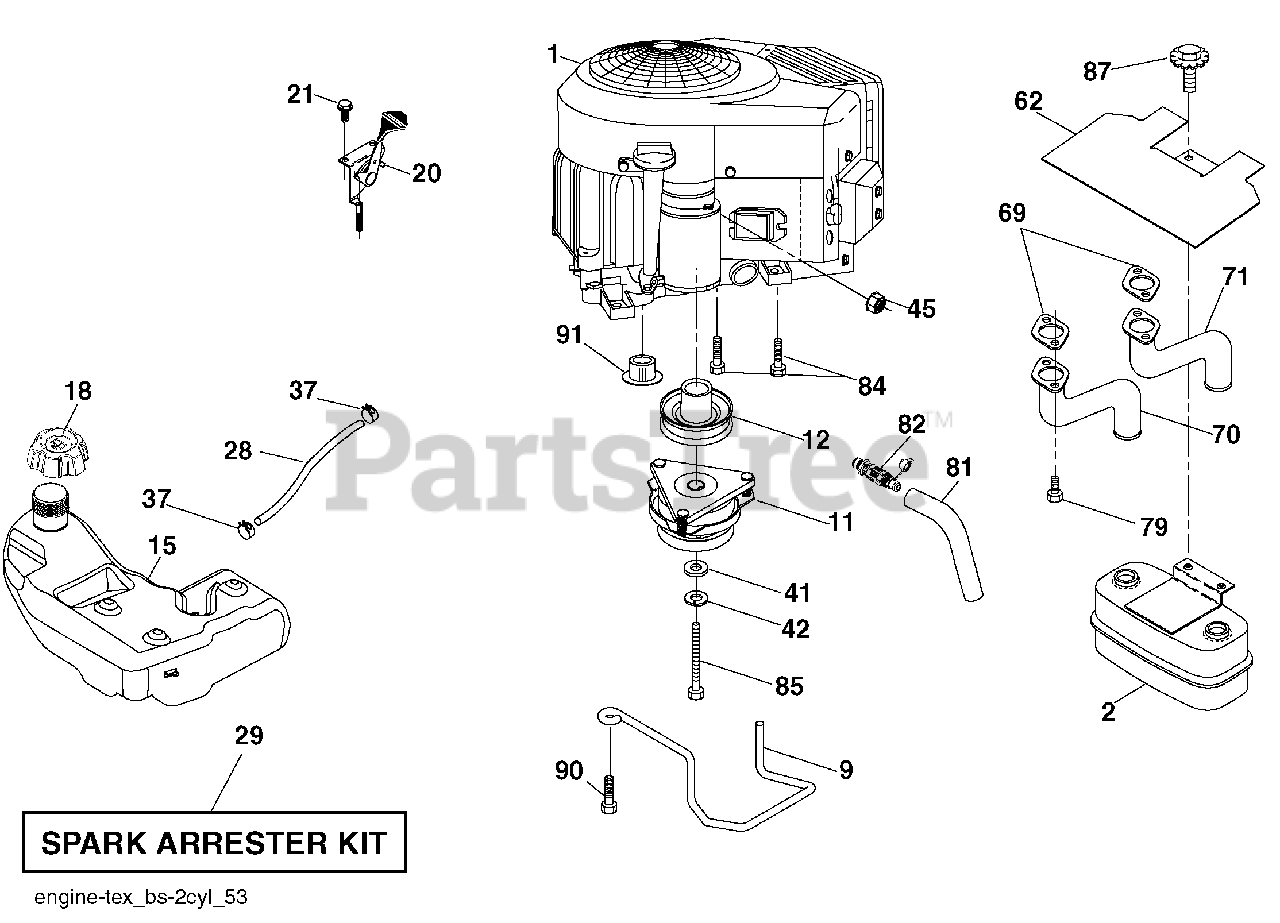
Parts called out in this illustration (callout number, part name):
2	Muffler
9	Keeper Belt Engine
11	Clutch Electric
12	Pulley Engine
15	Tank Fuel 3.0
18	Cap Asm
20	Control Throttle
21	Screw #10 x 0.750 BOS Thread
28	Fuel Line
29	Spark Arrester Kit
37	Clamp Hose
41	Washer 1-1/2 x 15-32 x .250
42	Washer Lock 7/16
45	Nut Keps Hex 1/4-20 unc
62	Shield Heat Muffler
69	Gasket
70	Exhaust Tube RH
71	Exhaust Tube LH
79	Screw Socket Head 5/16-18 x 1
81	Tube Drain Oil Easy
82	Valve Drain Oil
84	Screw 3/8-16 x 1-1/4
85	Bolt Hex 7/16-20 x 4 x 5 Ga.-1.5
87	Bolt 5/16-18 x 3/4
90	Screw 3/8-16 x 1
91	Bushing
